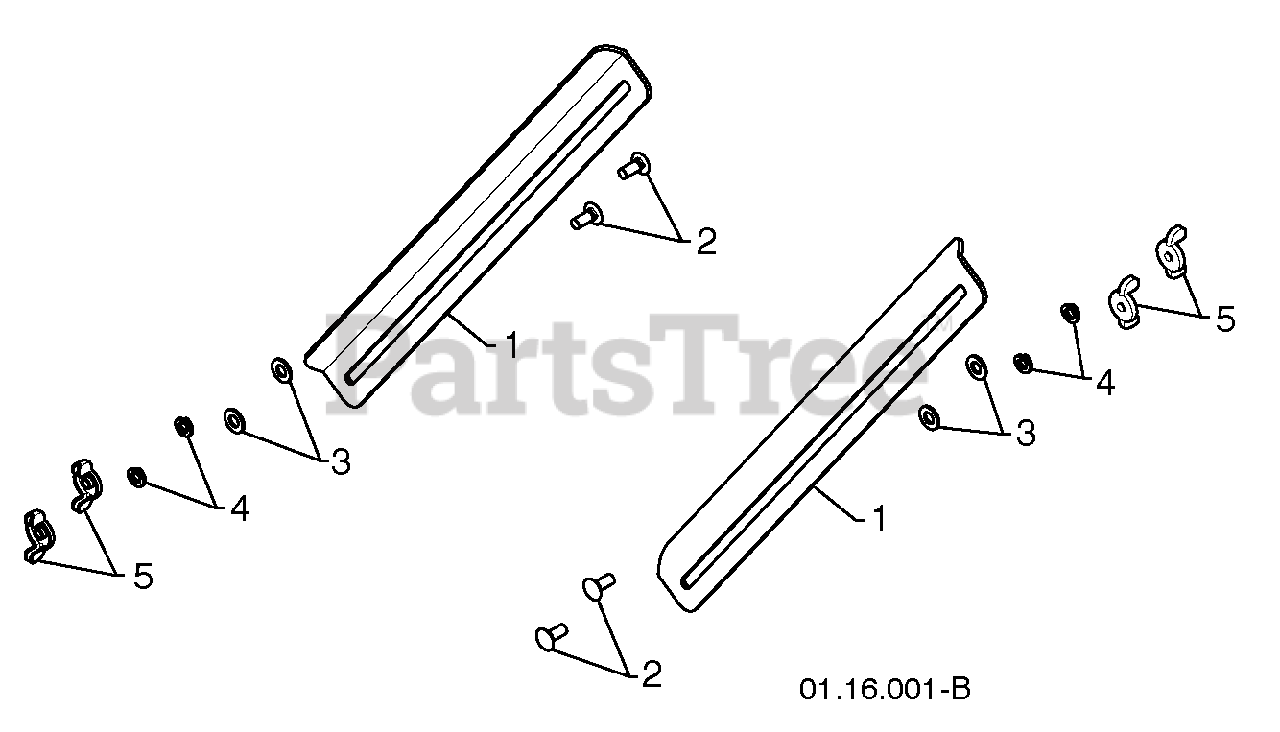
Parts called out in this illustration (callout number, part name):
1	DRIFT CUTTER BAR
2	CARRIAGE BOLT 5/16-18 X .750
3	PLASTIC WASHER
4	LOCKWASHER 5/16
5	NUT 5/16-18
